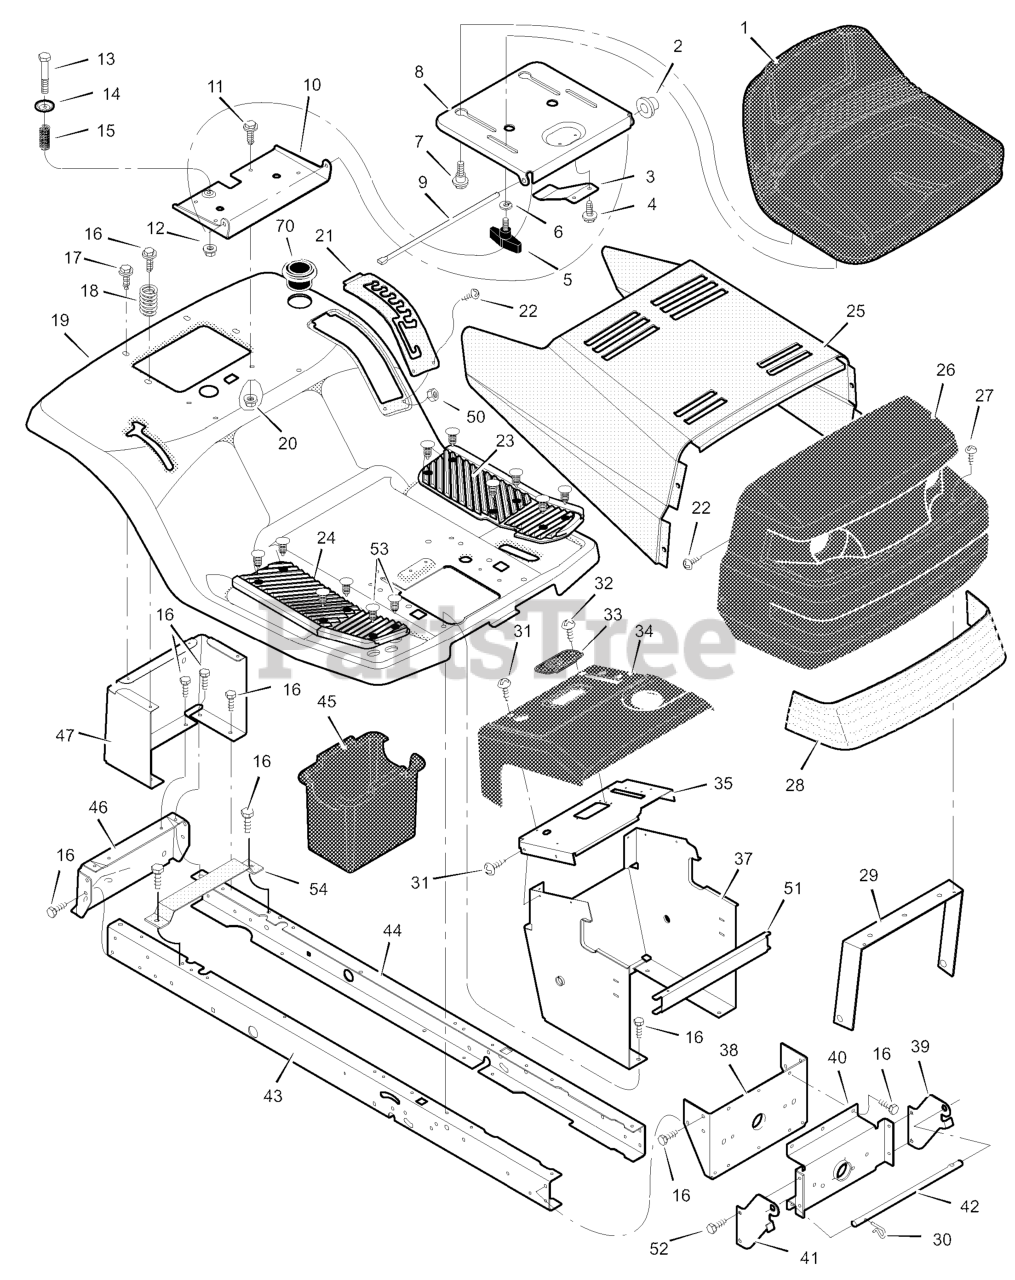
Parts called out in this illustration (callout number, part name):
1	Seat
2	Cap, Push On
5	Bolt, Wing
6	Washer
7	Bolt, Shoulder
8	Support, Seat
9	Rod, Pivot
10	Bracket, Pivot
11	Bolt
13	Bolt, Shoulder
15	Spring
19	Deck, Seat
20	Nut
21	Plate, Index
22	Screw
23	Mat, Left
24	Mat, Right
26	Grille Assembly
29	Brace, Grille
30	Pin, Hair
31	Screw
33	Bearing, Steering
35	Plate, Dash
36	Panel, Access
37	Support, Dash
38	Bracket, Rear Hanger
39	Support, Left Grille
40	Axle, Hanger
41	Support, Right Grille
42	Rod, Pivot
43	Frame, Right
44	Frame, Left
45	Container, Battery
46	Plate, Hitch
47	Panel, Rear
53	Fastener, Panel
54	Support, Battery
70	Holder, Cup
